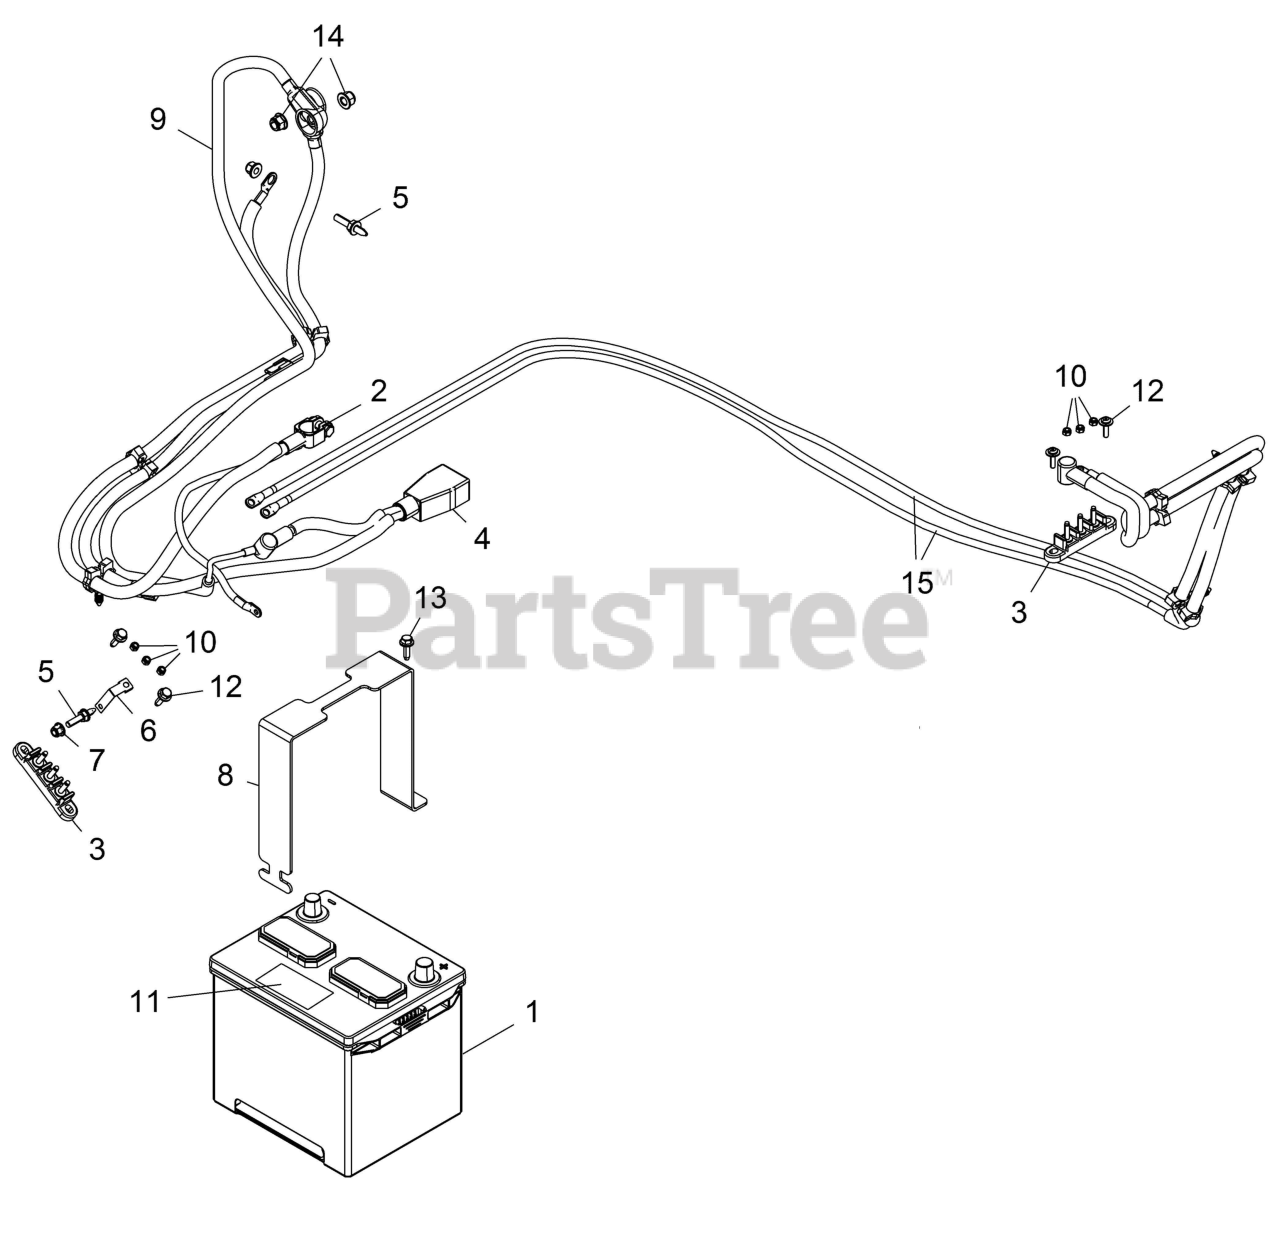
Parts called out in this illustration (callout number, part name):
1	BATTERY-575 CCA,FLOODED,FILLED
2	ASM.,CABLE, BAT TO GROUND/TERM
3	BLOCK, TERMINAL, 3 POST,TALL
4	CABLE, ALTERNATOR, BATTERY
5	STUD-M6X1.0X19-M6 TAPTITE
6	STRAP-GROUND
7	NUT-M6 FLANGE,NYLOK
8	BRKT-BATTERY STRAP GALV
9	CABLE, BATTERY TO ALT.
10	NUTS-10-32 KEPS
11	DECAL, BATTERY
12	SCR-10-24X3/4 PH/TX/TRI-SEMS Y
13	SCR-M6X1.0X20,HXHD,FLG,TDFM,BL
14	NUT-M8X1.25,HXFLG,NYLON INS
15	CABLE-TERMINAL BLOCK,GRND,ACC.
